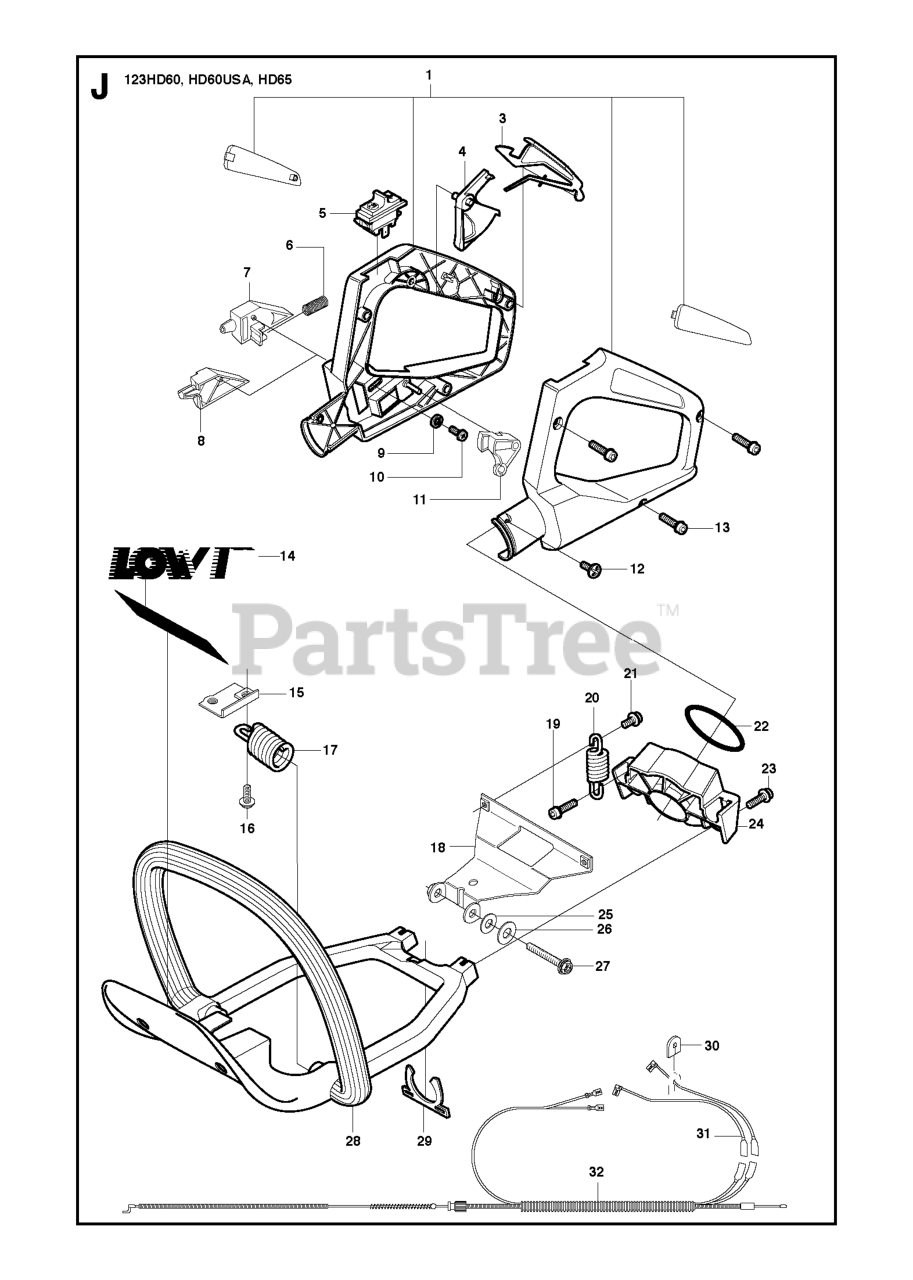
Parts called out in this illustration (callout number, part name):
1	REAR HANDLE COMPLETE
3	THROTTLE LOCK
4	THROTTLE TRIGGER
5	START/STOP SWITCH
6	SPRING
7	HOLDER
8	COVER
11	PAWL
15	STAY - L
15	ROD/STAY
16	SCREW M5 X 10
17	VIBRATION ABSORBER
18	%ROD
20	VIBRATION ABSORBER
21	SCREW M5 X 10
26	WASHER - M6
31	SHORTING LEAD
32	%WIRING ASSEMBLY
